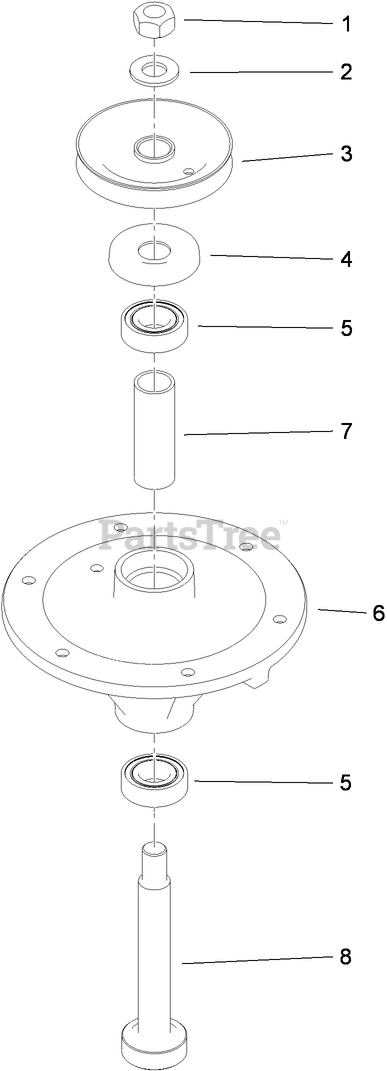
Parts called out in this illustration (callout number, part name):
1	NUT-HEX
2	WASHER
3	PULLEY ASM
4	SHIELD-BEARING
5	BEARING-BALL
6	HOUSING-SPINDLE
7	SPACER-BEARING
8	SHAFT-SPINDLE
